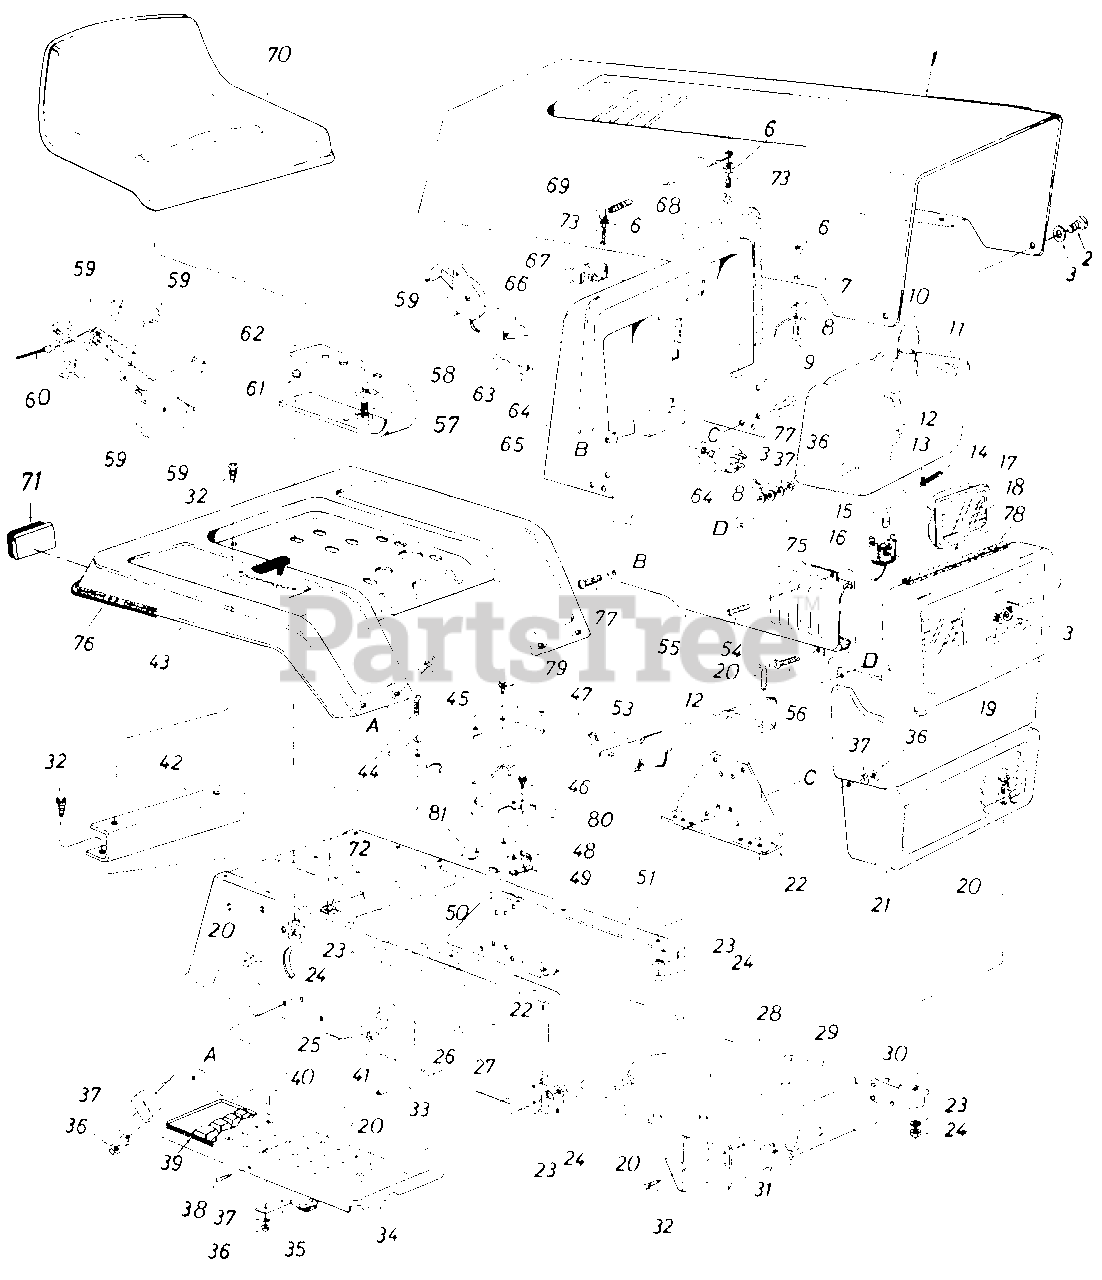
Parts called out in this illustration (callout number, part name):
1	Hood
2	Hex Scr. 1/4-20 x .62" Lg.
3	Fl-Wash. .296" I.D. x .62" O.D.
6	Hex Sems Nut #10-24 Thd.
7	Fl-Wash. .203" I.D. x .41" O.D. x .040
8	Hood Stop
9	Truss Hd. Scr. #10-24 x 1/2" Lg.*
10	Fuel Cap Gauge
11	Fuel Tank
12	Tie Strap
13	Hose Clamp
14	Fuel Line
15	Lamp
16	Soc ket
17	Headlight Housing
18	Lens
19	Hex L-Nut 1/4-20 Thd.
20	Hex Bolt 5/16-18 x .75" Lg.
21	Grille
22	Dash Support Bracket
23	L-Wash. 5/16" I.D.
24	Hex Nut 5/16-18 Thd.
25	Battery Strap Hook
26	Battery Hold Down Strap
27	12V Battery
28	Lower Frame
29	Front Pivot Brk't.
30	Grille Mount Brk't. L.H.
33	Running Board Rod
34	Running Board
35	Blade Brake Ass'y.
36	Hex Nut 1/4-20 Thd.
37	L-Wash. 1/4" I.D.
38	Truss Mach. Scr. 5/16-18 x .75" Lg.
39	Foot Pad
40	Carriage Bolt 1/4-20 x .62" Lg.*
41	R.H. Side Frame
42	Fender Mount Brace
43	Rear Fender
44	Truss Mach. Tap Scr. #10 x .50" Lg.
45	Carriage Bolt 1/4-20 x .50" Lg.*
46	Truss Hd. Scr. #10-24 x .50" Lg.*
47	Transmission Panel
48	Reverse Safety Switch
49	Insulator Nut Plate
50	Hitch Plate
51	L.H. Side Frame
53	Fuel Tank Support
54	Truss Hd. Scr. 1/4-20 x .75" Lg.*
55	Side Cover R.H.
56	Truss Mach. Scr. 1/4-20 x .50" Lg.
57	Hex Bolt 1/2-13 x 1.0" Lg.
58	L-Wash. 1/2" I.D.
59	Throttle Control Box Ass'y.
60	Throttle Control Wire
61	Hex Bolt 5/16-18 x 1.00" Lg.*
62	Seat Spring 5.5" High
63	Ignition Key
64	Ignition Switch
65	Dash Panel
66	Light Switch
67	Ammeter
68	Trim Strip 27"
69	Hood Spring
70	Seat Ass'y.
71	Rear Fender Reflectors
72	Speed Nut #10Z
73	Hex Scr. #10-24 x 1.0" Lg.
75	Tie Strap Grille/Side Panel
76	Trim Strip 81"
77	Hex Wash. Hd. Tap Scr. 1/4 x .75" Lg.
78	Foam Strip 3/8 x 1 x 14" Lg.
79	Truss Mach. Scr. 1/4-20 x .75" Lg.
80	Gear Selection Plate
81	Clamping Plate
